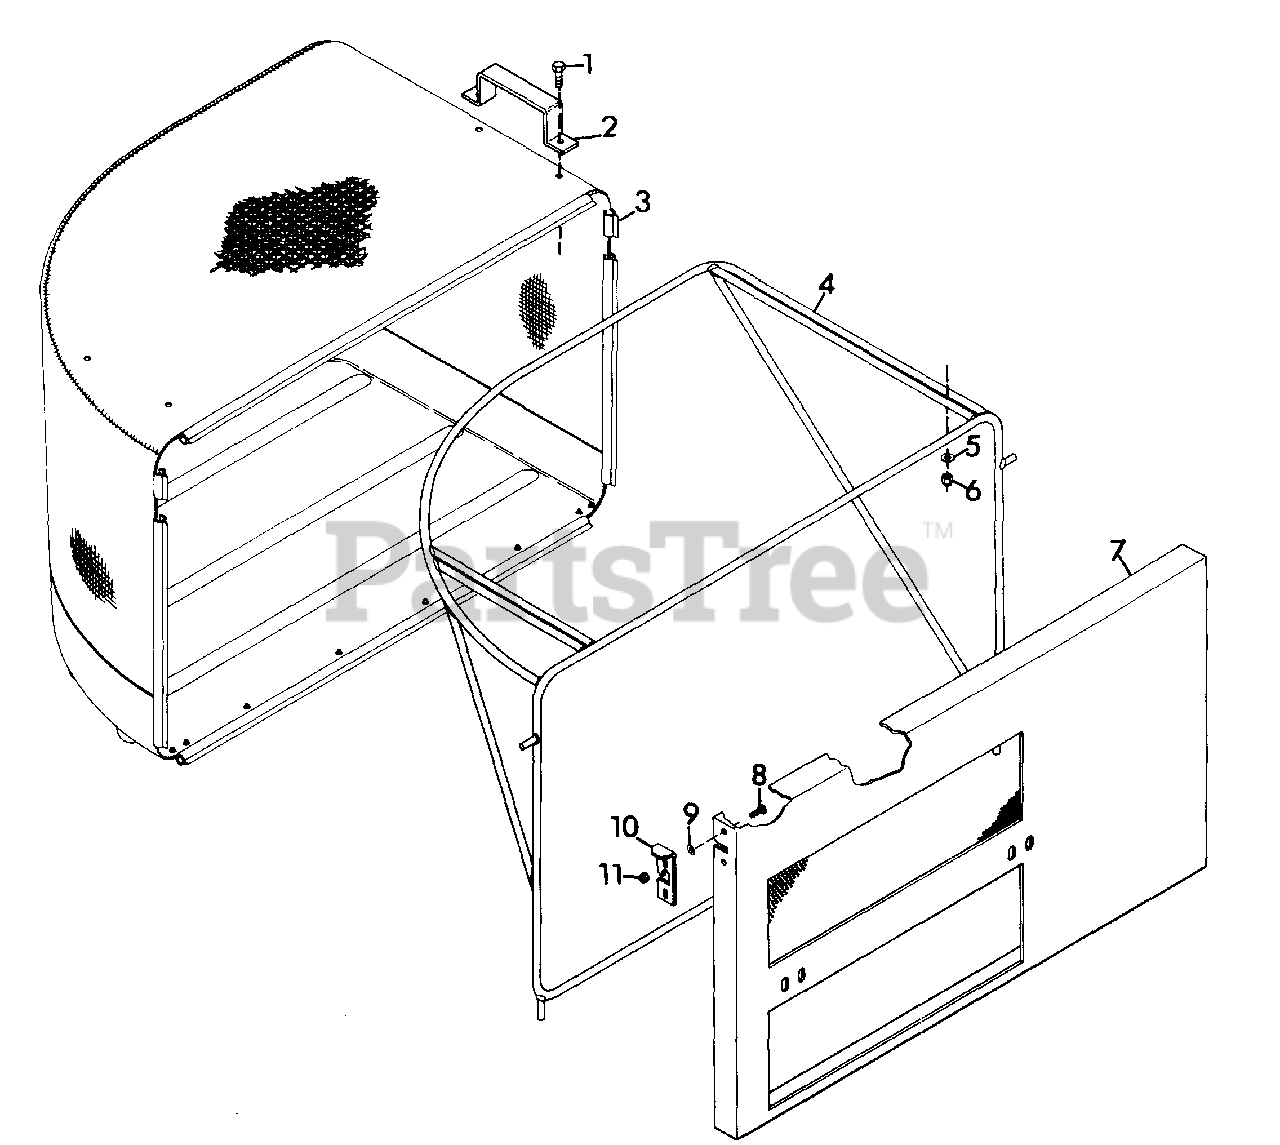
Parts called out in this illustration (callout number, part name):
1	BOLT, HEX 1/4-20X1.00
2	HANDLE, HOPPER
3	ASSEMBLY, PAN AND CATCHER
4	FRAME, CATCHER
5	WASHER, HANDLE
6	NUT, LOCK 1/4-20
7	WELDMENT, CATCHER SUPPORT
8	SCREW, MACH. 10-24X.625
9	WASHER, 1/4" SPRING
10	LATCH, CATCHER LEFT
11	NUT, LOCK 10-24
NS	LATCH, CATCHER RIGHT
